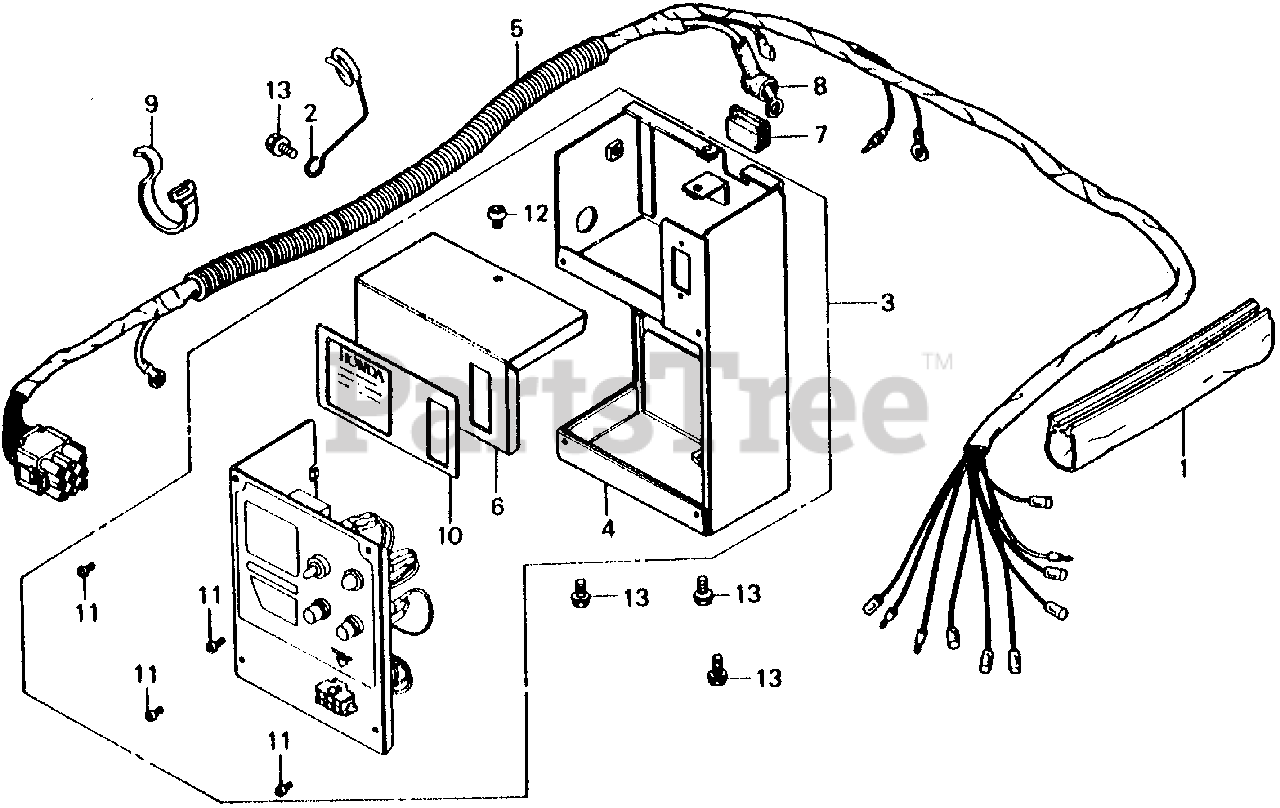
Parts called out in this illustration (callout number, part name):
1	TUBE, FASTENER
2	CLAMP, STARTER CABLE
3	BOX ASSY., CONTROL *NH116M* (URBAN SILVER METALLIC) (NOT AVAILABLE)
4	COVER, CONTROL BOX *NH116M* (URBAN SILVER METALLIC)
5	WIRE HARNESS
6	COVER, BOX (UPPER) *NH116M* (URBAN SILVER METALLIC)
8	COVER, TERMINAL
9	BAND, WIRE
10	PLATE, CONTROL PANEL (UPPER)
11	SCREW, PAN (4X6)
12	SCREW, PAN (4X6) (SOURCE: VINTAGE PARTS INC.)
13	BOLT, FLANGE (6X10)
